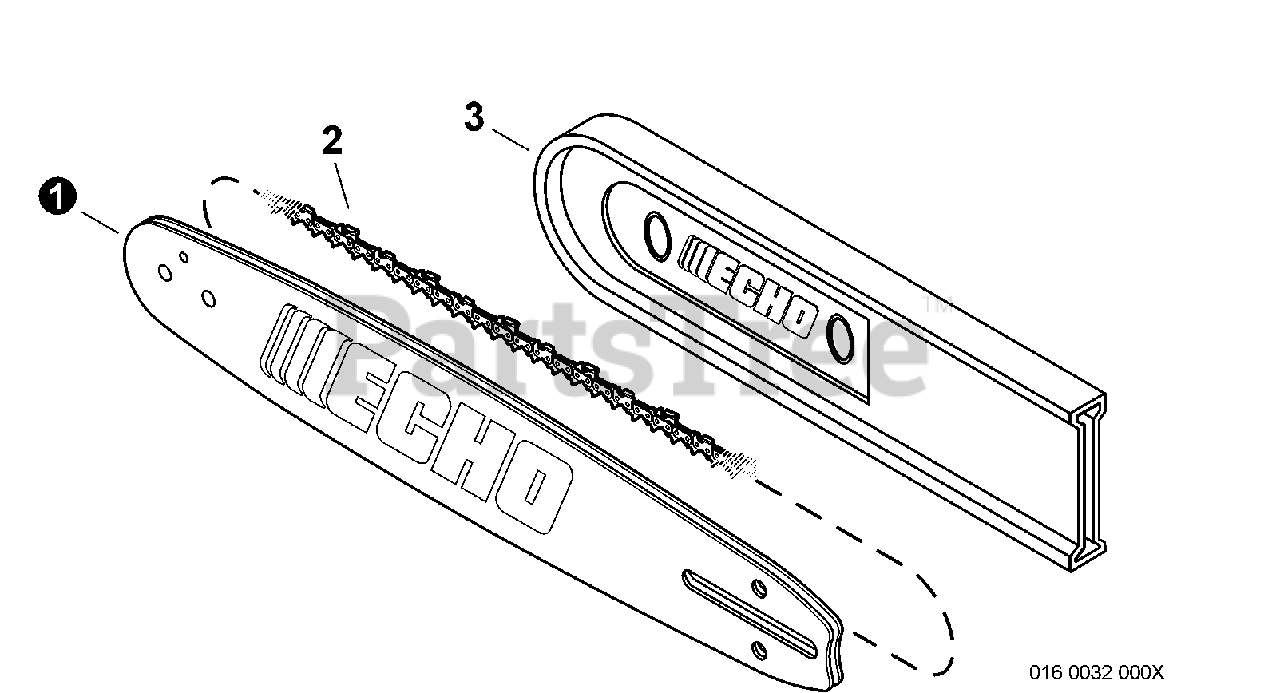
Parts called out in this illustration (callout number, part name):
1	GUIDE BAR, 38RD58-325
1	GUIDE BAR, 43RD58-325
2	SAW CHAIN 21BPX-64E
2	SAW CHAIN 21BPX-72E
3	SCABBARD
